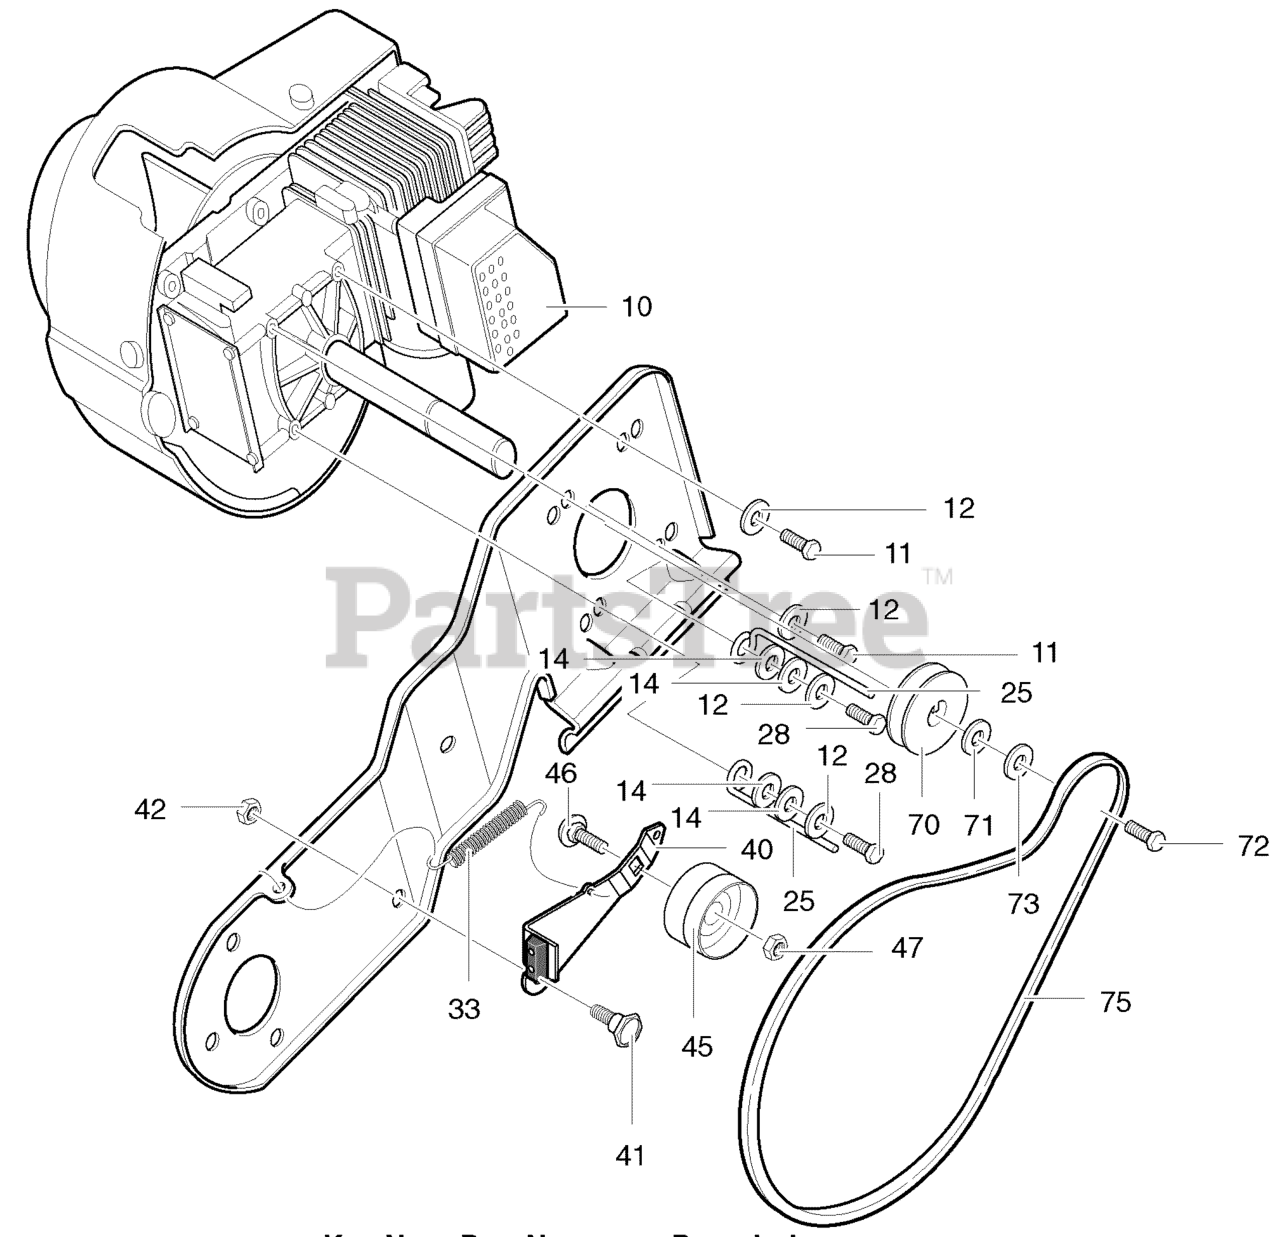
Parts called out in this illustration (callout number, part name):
10	ENGINE
11	SCREW, 5/16-18 x 0.75
12	WASHER
14	WASHER, FLAT
25	GUIDE, BELT
33	SPRING, IDLER BRAKE
40	ASSY, IDLER BRAKE ARM
41	BOLT
42	NUT, 5/16-18
45	PULLEY, IDLER
46	BOLT, CARRIAGE
47	NUT
70	PULLEY, ENGINE
71	WASHER, BELLEVELLE
72	SCREW, 5/16-24 x .75
73	WASHER, SPLTLK
75	BELT, V 3L 34.8"
